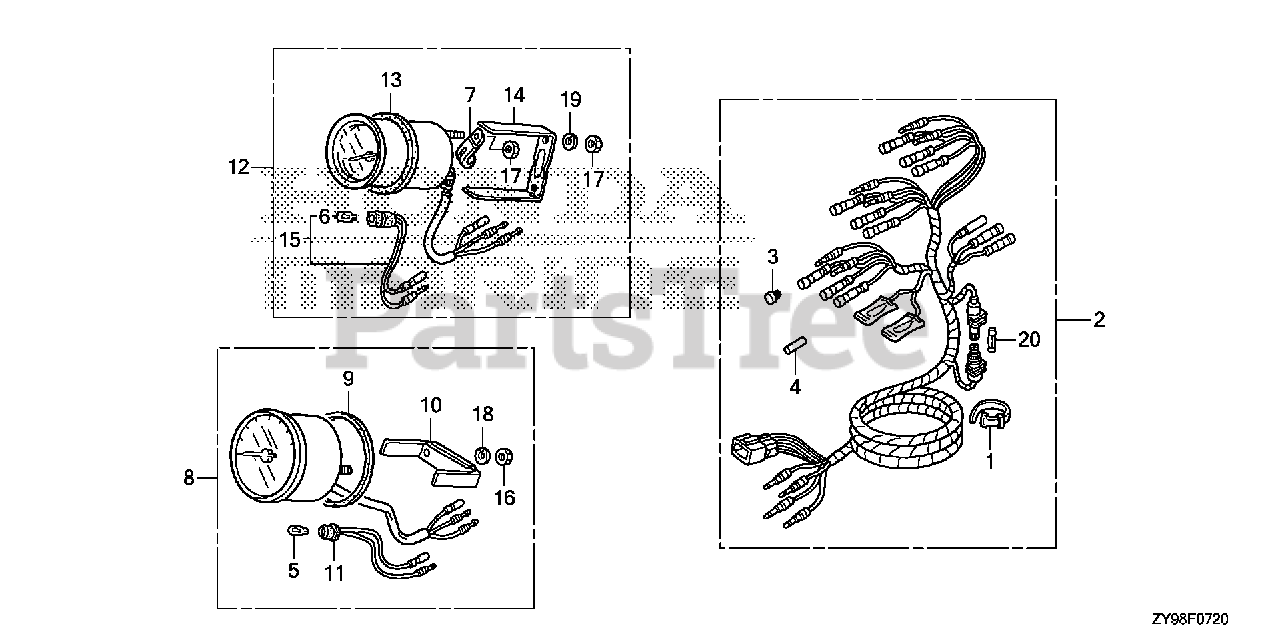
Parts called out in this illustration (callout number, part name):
1	BAND B1, WIRE
2	HARNESS ASSY., METER (A)
3	PLUG, CONNECTOR (INNER)
4	PLUG, CONNECTOR (OUTER)
5	BULB, WEDGE BASE (T10) (12V 1.7W) (STANLEY)
6	BULB, WEDGE BASE (12V 1.7W)
7	CLAMP
8	TACHOMETER ASSY.
9	GASKET
10	BRACKET
11	SOCKET
12	METER ASSY., TRIM
13	GASKET
14	BRACKET
15	SOCKET
16	NUT, HEX. (5MM)
17	NUT, HEX. (4MM)
18	WASHER, SPRING (5MM)
19	WASHER, SPRING (4MM)
20	FUSE A (10A)
